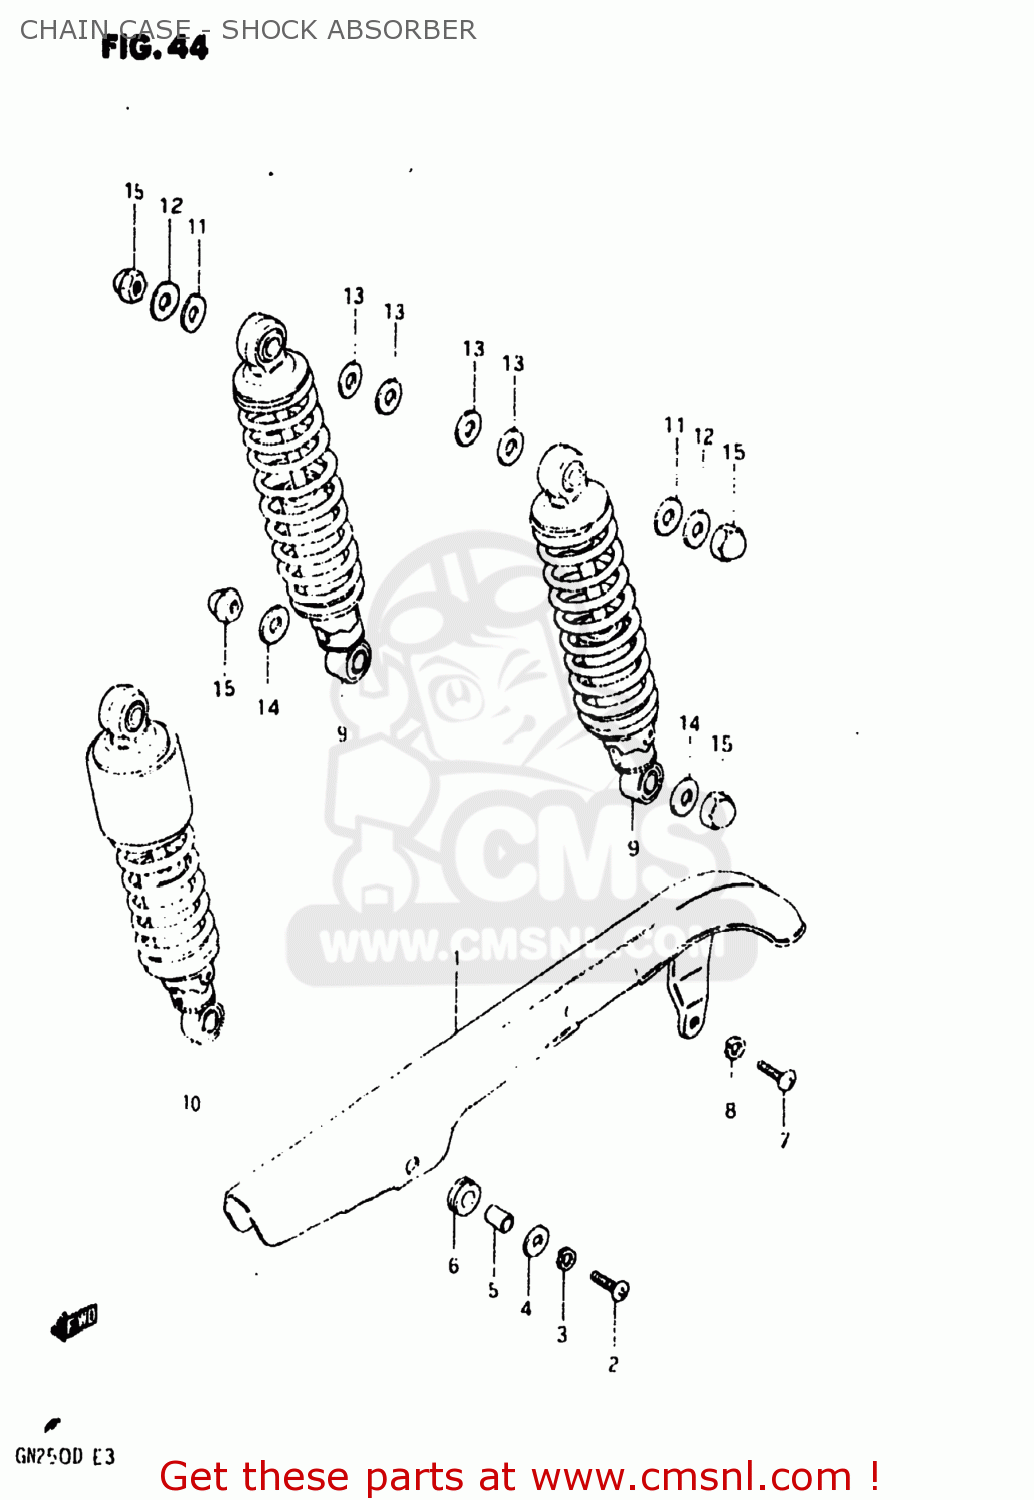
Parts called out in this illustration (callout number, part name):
1	CASE,CHAIN
2	SCREW
3	LOCK WASHER
4	WASHER (6.5X20X1.2)
5	SPACER (7X9X7)
6	CUSHION
7	SCREW
8	LOCK WASHER
9	ABSORBER ASSEMBLY,REAR SHOCK
10	ABSORBER ASSY,RR SHOCK
11	WASHER
12	WASHER(10.5X24X3.2)
13	WASHER
14	WASHER
15	NUT, LOWER LH
